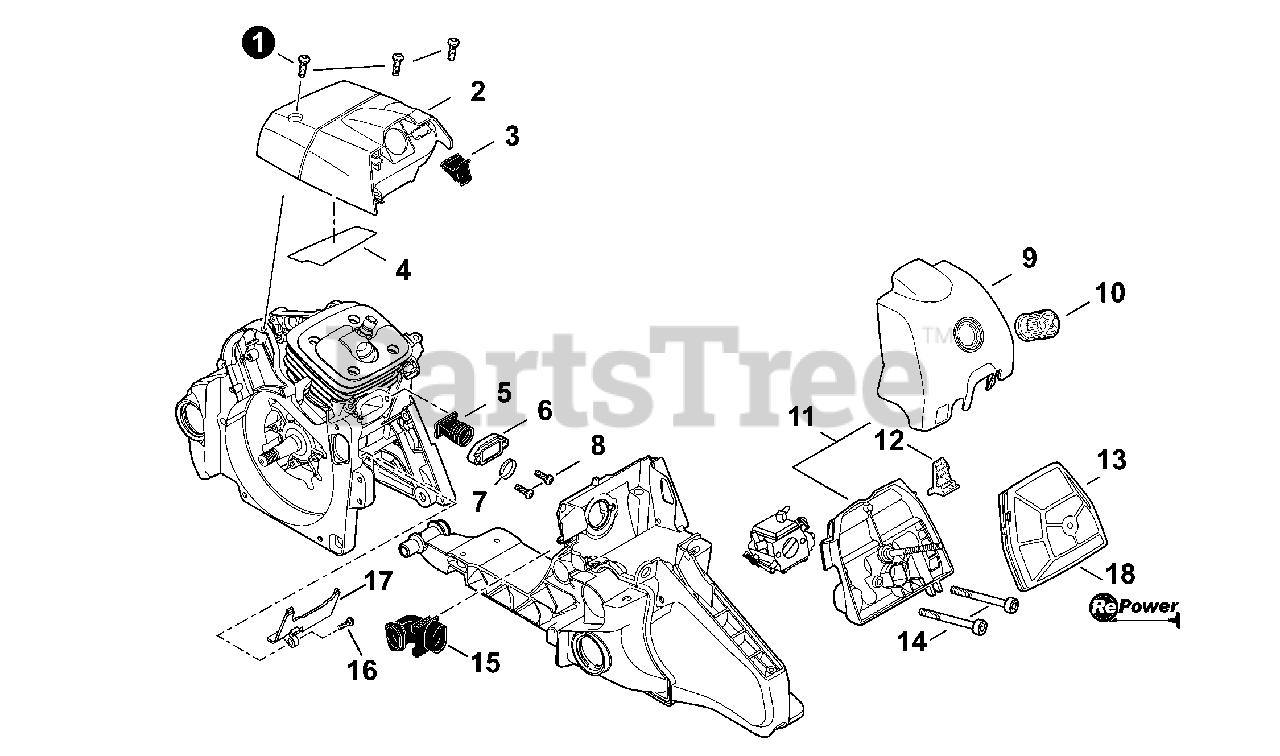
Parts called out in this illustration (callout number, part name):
1	BOLT, TORX 5×16
2	COVER, ENGINE
3	PIPE, INTAKE
4	SHIELD, HEAT 75×32×0.15
5	BELLOWS, INTAKE
6	HOLDER, BELLOWS
7	COLLAR 18.6×20.4×4
8	BOLT, TORX 5×16
9	COVER, AIR FILTER
10	KNOB, AIR FILTER COVER
11	CASE, AIR FILTER
12	SHUTTER, AIR
13	FILTER ASSY, AIR
13	FILTER ASSY, AIR - COLD WEATHER
14	BOLT, TORX 5×50
15	PIPE, AIR INTAKE
16	BOLT, TORX 5×16
17	GUIDE, AIR
18	TUNE-UP KIT - REPOWER
